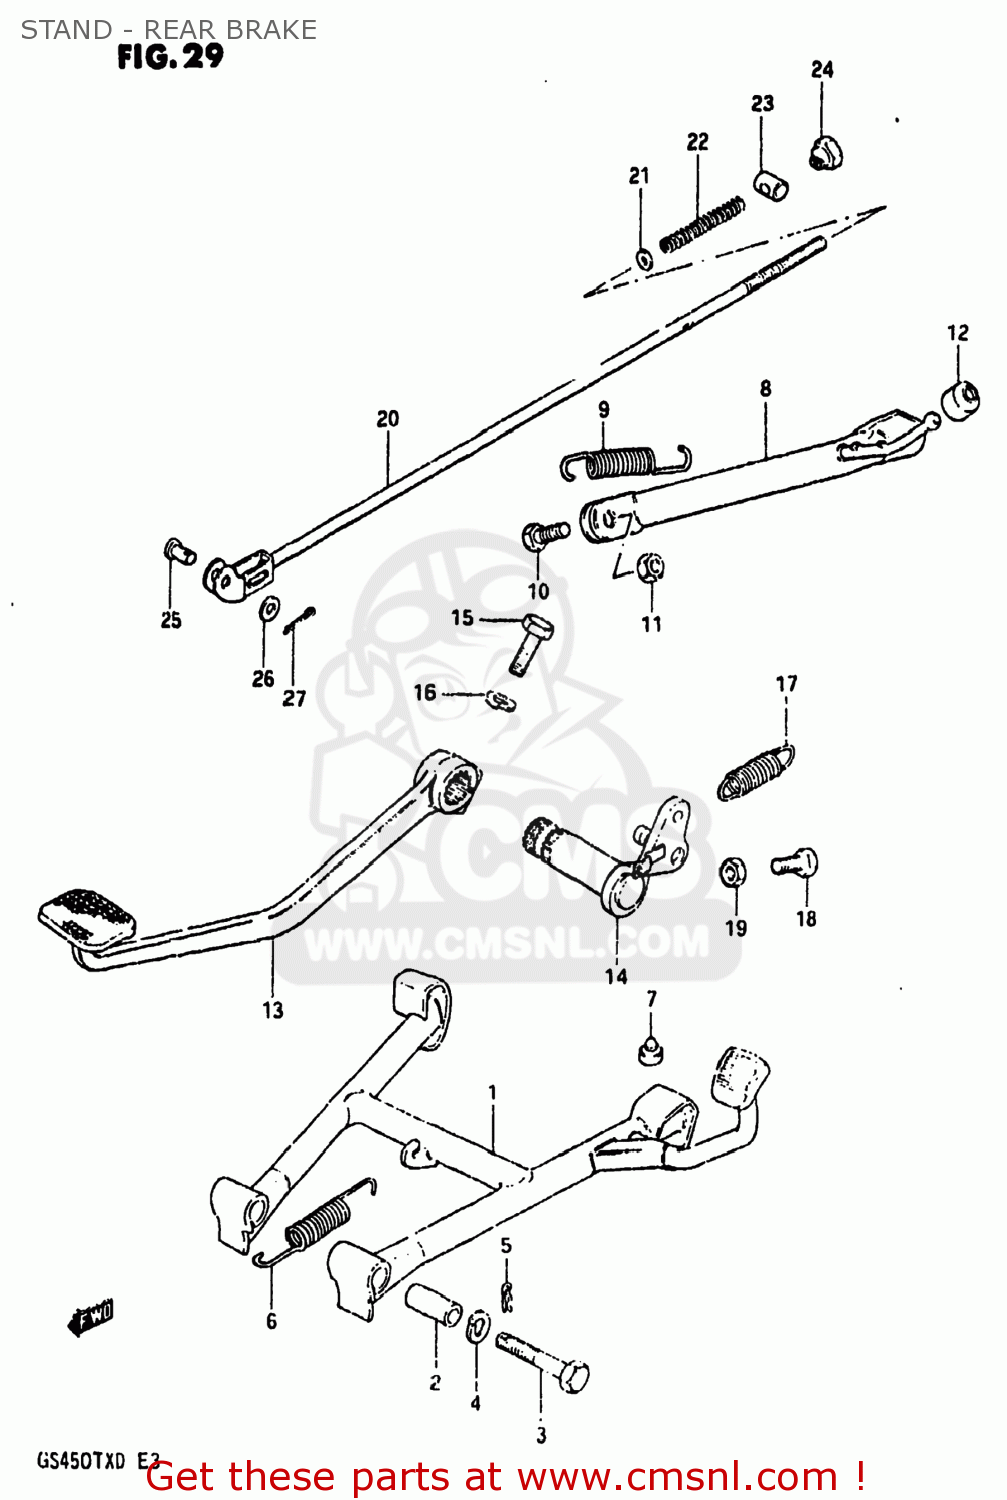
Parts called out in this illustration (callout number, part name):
1	STAND,CENTER
2	SPACER(10X16X38.8)
3	BOLT
4	LOCK WASHER
5	CLIP
6	SPRING
7	CUSHION
8	STAND,SIDE
9	SPRING
10	BOLT(10X30)
11	NUT
12	CUSHION
13	PEDAL,BRAKE
14	ARM,BRAKE PEDAL
15	BOLT
16	LOCK WASHER
17	SPRING
18	BOLT
19	NUT
20	ROD ASSY,RR BRAKE
21	WASHER
22	SPRING
23	PIN
24	NUT (6MM)
25	PIN(L:13.5)
26	WASHER
27	PIN 20X20
